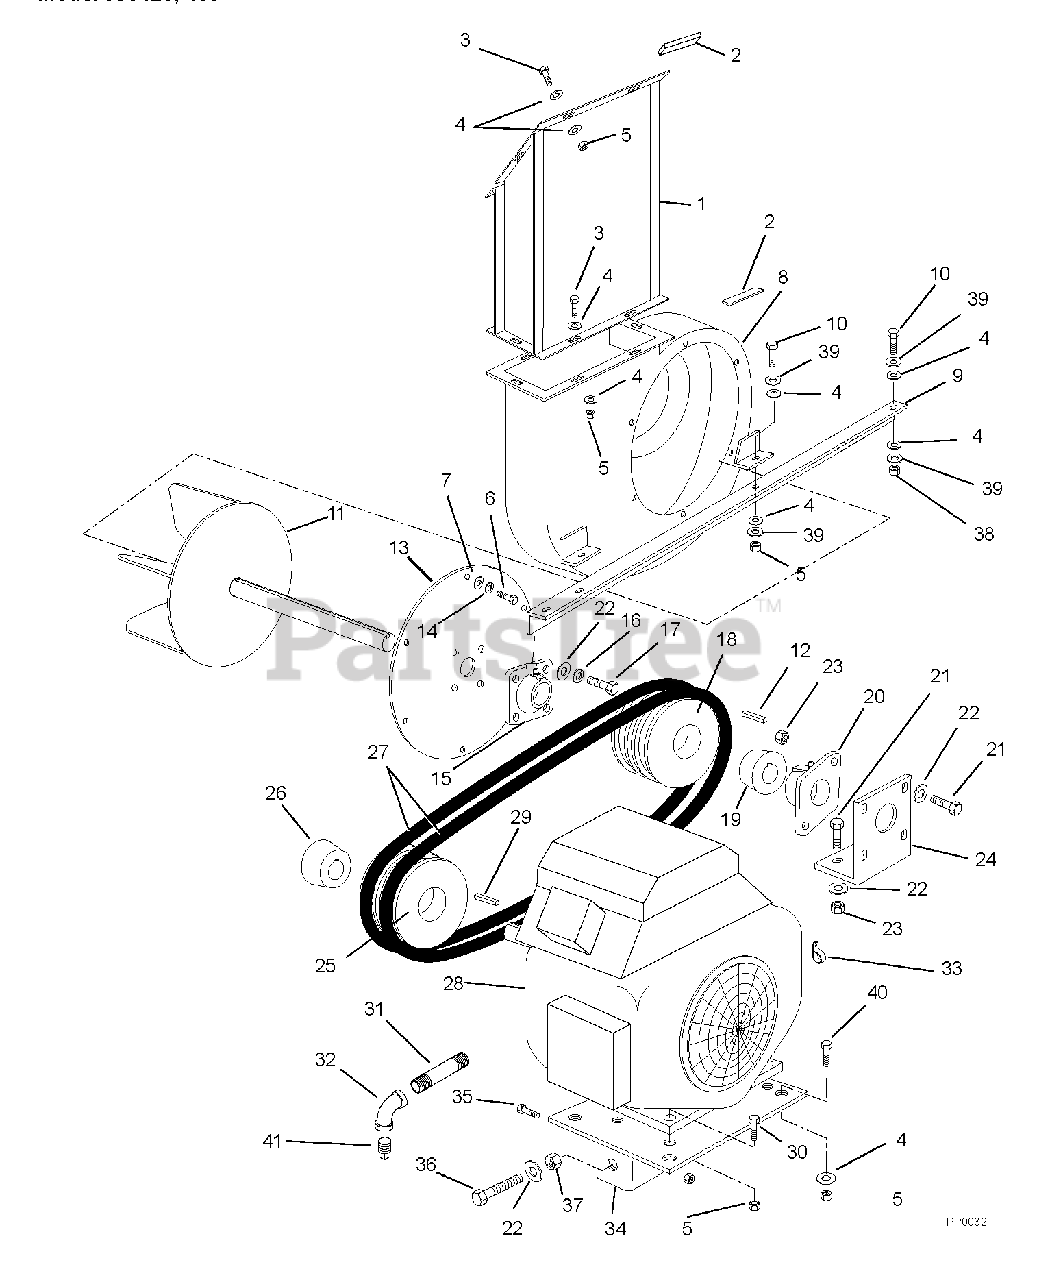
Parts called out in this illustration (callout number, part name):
1	Weldment, Discharge Chute
2	Gasket Material 1.25 x .188
3	Bolt, Hex .38-16 x .75 Grade 5
4	Washer, Flat .38
5	Nut, Hex Nylock .38-16
6	Cap Screw, Hex Head .312-16 x .75
7	Washer, Flat .312
8	Weldment, Blower
9	Support Beam, Blower
10	Cap Screw, Hex Head .38-16 x 1.00
11	Fan, Impeller
12	Key, Straight .38 x .38 x 2.0
13	Weldment, Fan Cover
14	Washer, Locking .312
15	Bearing, Four-Bolt Flange
16	Washer, Lock .438
17	Cap Screw, Hex Head .44-14 x 1.25 Grade 8
18	Pulley, V 2G 3V 6.5 Taper Lock
19	Bushing, Drive Sheave
20	Bearing, Two-Bolt Flange
21	Cap Screw, Hex Head .50-13 x 1.50
22	Washer, Flat .50
23	Nut, Lock .50-13
24	Holder, Bearing
25	Pulley, V 2G 3V 5.5 Taper Lock
26	Bushing, Drive Sheave
27	V-Belt (Matched Set of Two)
28	Engine, 18 HP Kohler Command
29	Key .25 x .25 x 1.25
30	Cap Screw, Hex Head .38-16 x 1.75
31	Nipple .38 x 3.50
32	Elbow .375-18 NPTF
34	Weldment, Engine Base
35	Cap Screw, Hex Head .38-16 x 1.25
36	Cap Screw, Hex Head .50-13 x 5.00
37	Nut, Hex .50
38	Nut, Hex Serrated Flange .38-16
39	Washer, Hardened .50
40	Cap Screw, Hex Head .38-16 x 1.50
41	Plug, Oil Drain (Use drain plug supplied with engine)
